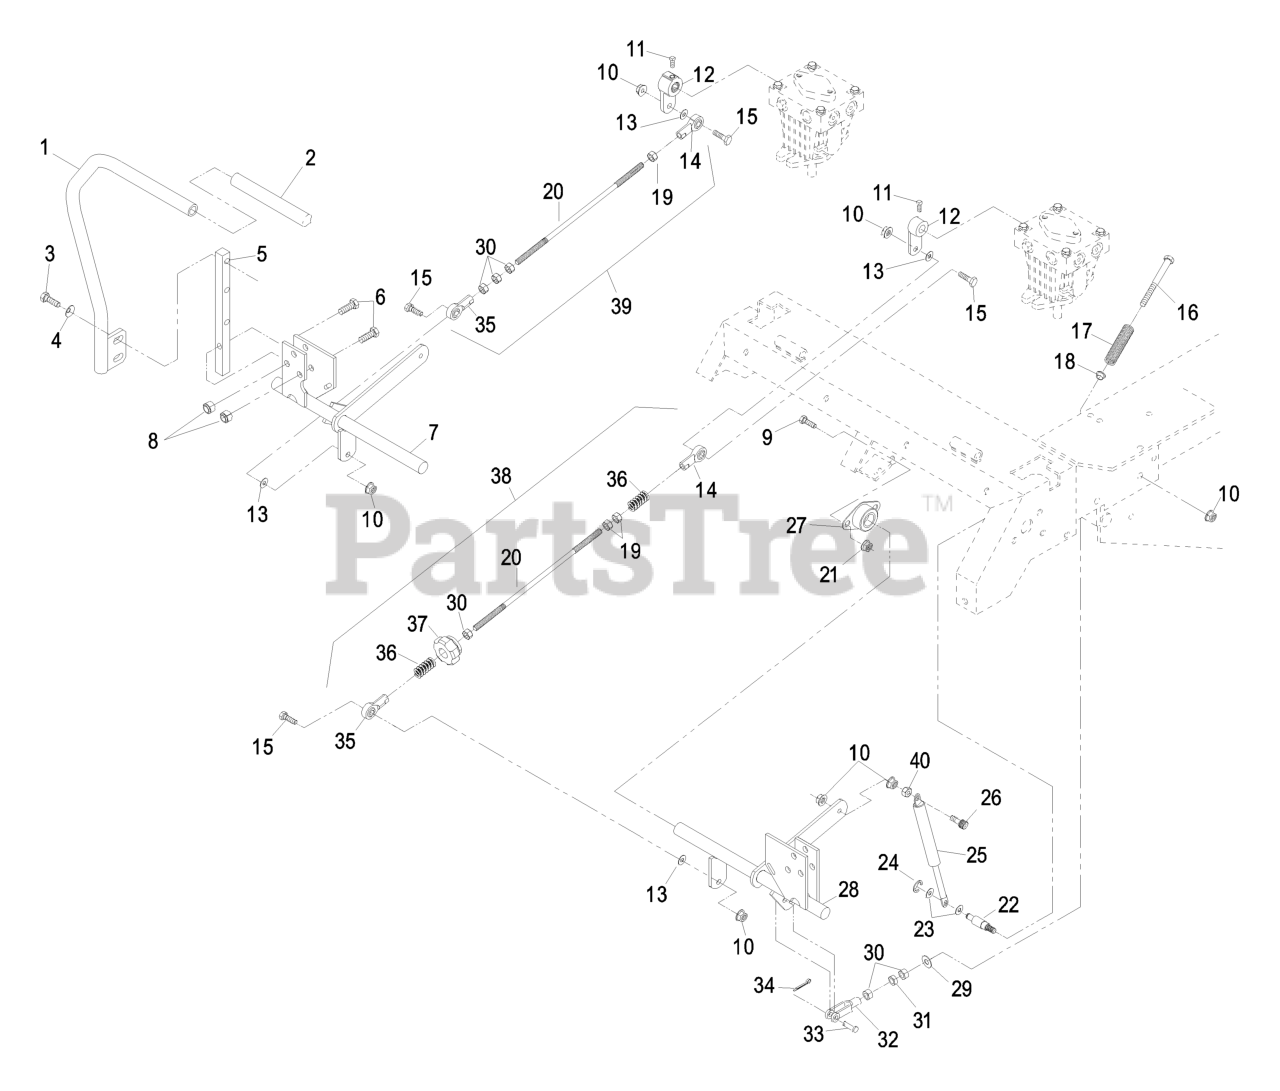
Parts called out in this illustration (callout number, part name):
1	ASM.RH LEVER/GRIP
2	GRIP-CONTROL, MOTION
3	SCREW-HH
4	WASHER-BELLEVILLE
5	ARM-SHAFT, CONTROL
6	SCREW-HH
8	NUT-LOCK, NI
9	SCREW-HH
11	SCREW-SET
12	ARM-CONTROL
13	WASHER-FLAT
14	BALLJOINT-LH
15	SCREW-HH
16	BOLT-RETURN, NEUTRAL
17	SPRING-RETURN, NEUTRAL
18	BUSHING-FLANGED
20	LINK-ROD, TRACKING
21	NUT-HHF, WHIZ
22	PIN-DAMPER
23	WASHER-PLAIN
24	RING-RETAINING, EXT
26	SCREW-HH
27	BEARING-FLANGE, SIDE
28	CONTROL-MOTION, LH
29	WASHER-FLAT
30	NUT-HEX
31	NUT-JAM
32	YOKE-ADJUSTABLE
33	PIN-CLEVIS
34	PIN-COTTER
35	BALLJOINT-RH
36	SPRING-COMPRESSION
37	KNOB-TRACKING
38	TRACKING ROD ASM
39	TRACKING ASM
40	NUT-HEX
